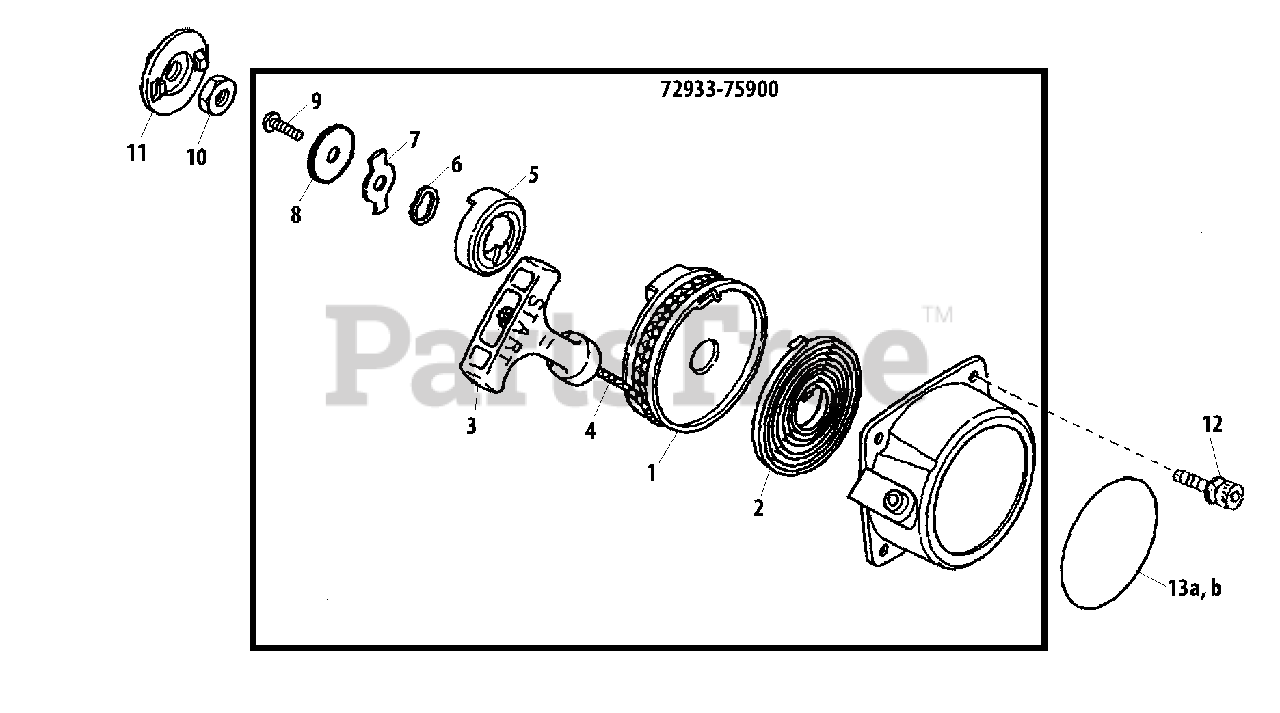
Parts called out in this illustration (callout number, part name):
1	REEL, ROPE
2	SPRING, RECOIL
3	GRIP, STARTER
4	ROPE, STARTER
5	RATCHET
6	WASHER, WAVE
7	RETAINER
8	WASHER 5 MM
9	SCREW 5 MM
10	NUT M8×1
11	PULLEY, STARTER
12	BOLT M4×12
13A	LABEL, SHINDAIWA PROFESSIONAL
13B	LABEL
72933-75900	STARTER ASSY, RECOIL
